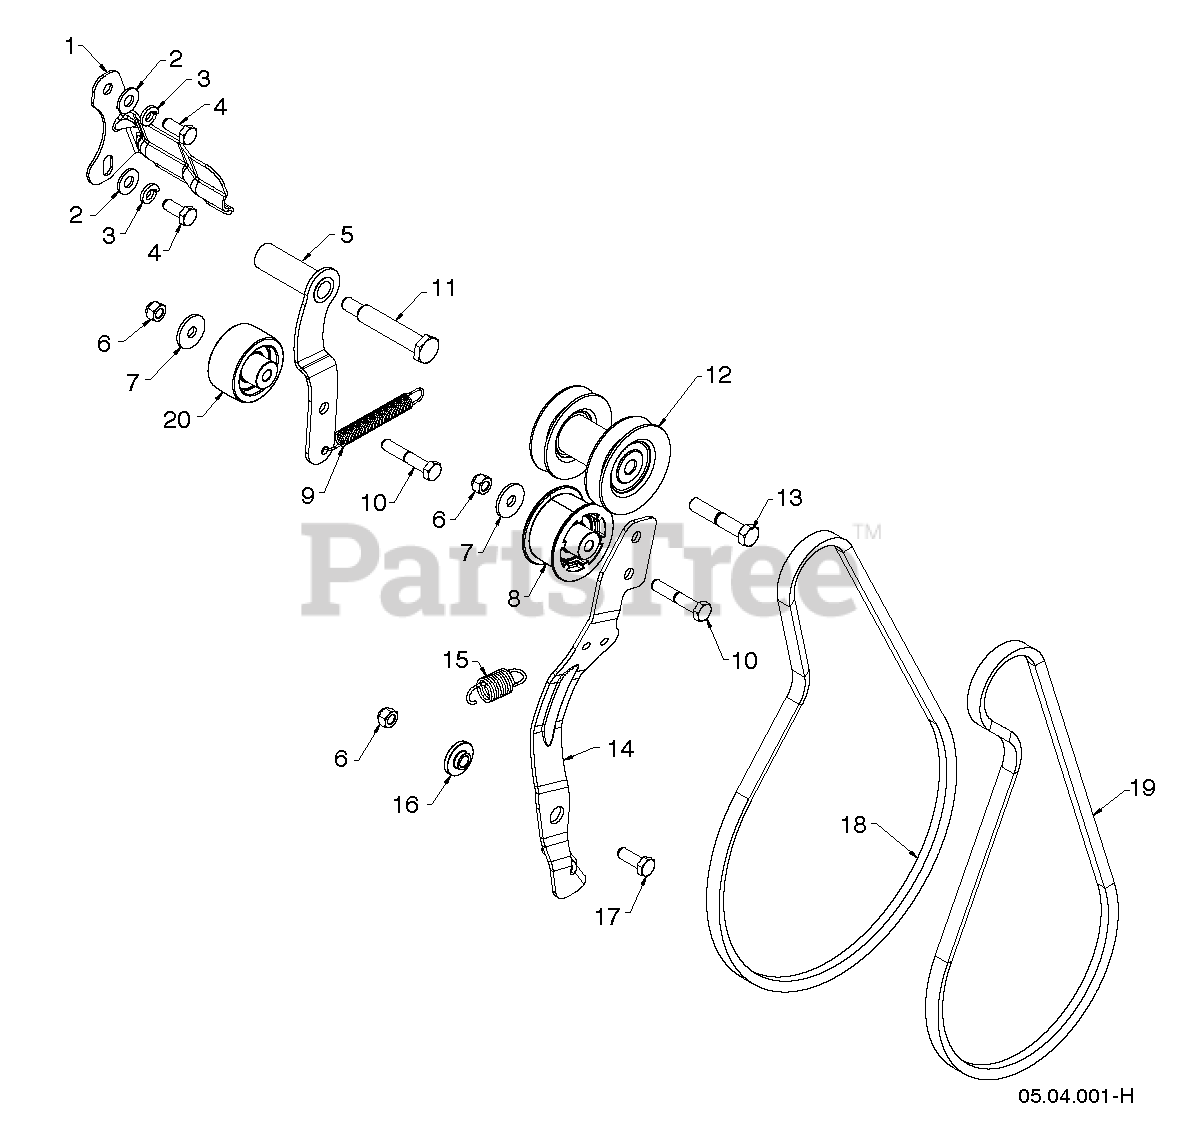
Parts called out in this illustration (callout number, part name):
1	BELT KEEPER BRACKET
2	WASHER M
3	WASHER.LOCK.HVY.HLCL.SPR.5/16
4	SCREW 5/16-24 X .75 GR5
5	ARM IDLER DRIVE WELDMENT_HOT
6	NUT.71038.31-18.HEX.NYLOCK
7	STEEL WASHER
8	PULLEY,IDLER,2.00 W SPA
9	SPRING RETURN IDLER ARM
10	BOLT, HEX 5/16-18X1-3/4
11	BOLT 5/16-24X2.25 HEX HEAD SHO
12	PULLEY.ASM.IMPELLER/DRIVE
13	BOLT.ENGINE.PULLEY
14	ARM.IDLER.AUTO-PH.676
15	SPRING RETURN, IDLER ARM, IMPE
16	BUSHING.BRAKE.ARM
17	BOLT
18	BELT.DRIVE.SNOW.DUAL
19	LOW CRANK IMPELLER BELT
20	PULLEY.IDLER.FLANG.2.O/SPACER
